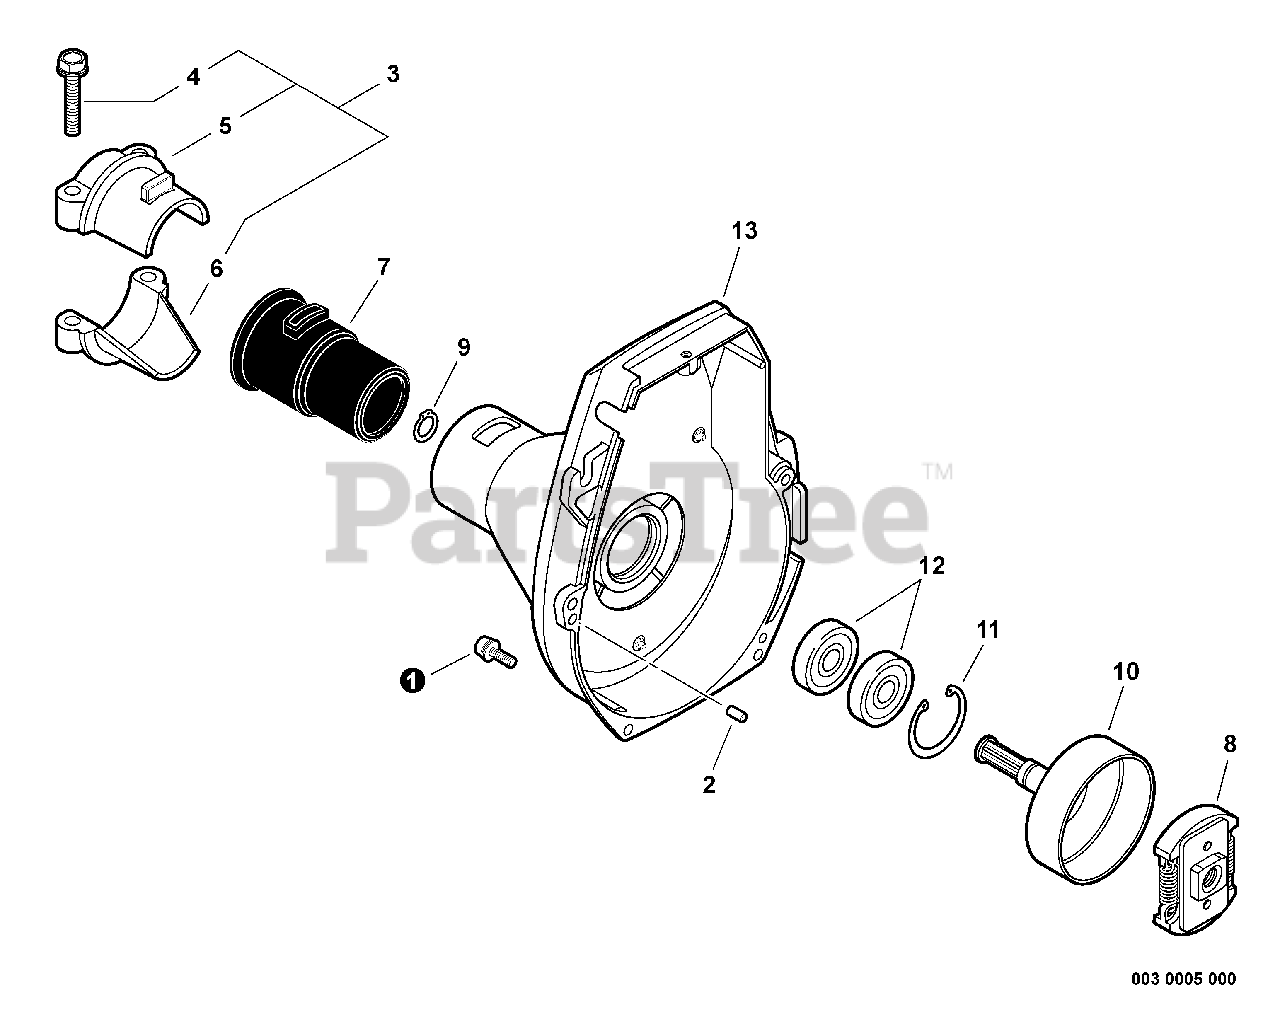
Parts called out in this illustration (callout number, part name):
1	BOLT 4×16
2	PIN, LOCATING 4
3	RETAINER KIT
4	BOLT - 5×25
5	HOLDER, MAIN PIPE - UPPER
6	HOLDER - LOWER
7	CUSHION Ø25
8	CLUTCH ASSY
9	RING, RETAINING - 12
10	DRUM, CLUTCH
11	RING, SNAP 28
12	BEARING, BALL 6001
13	COVER ASSY, FAN
